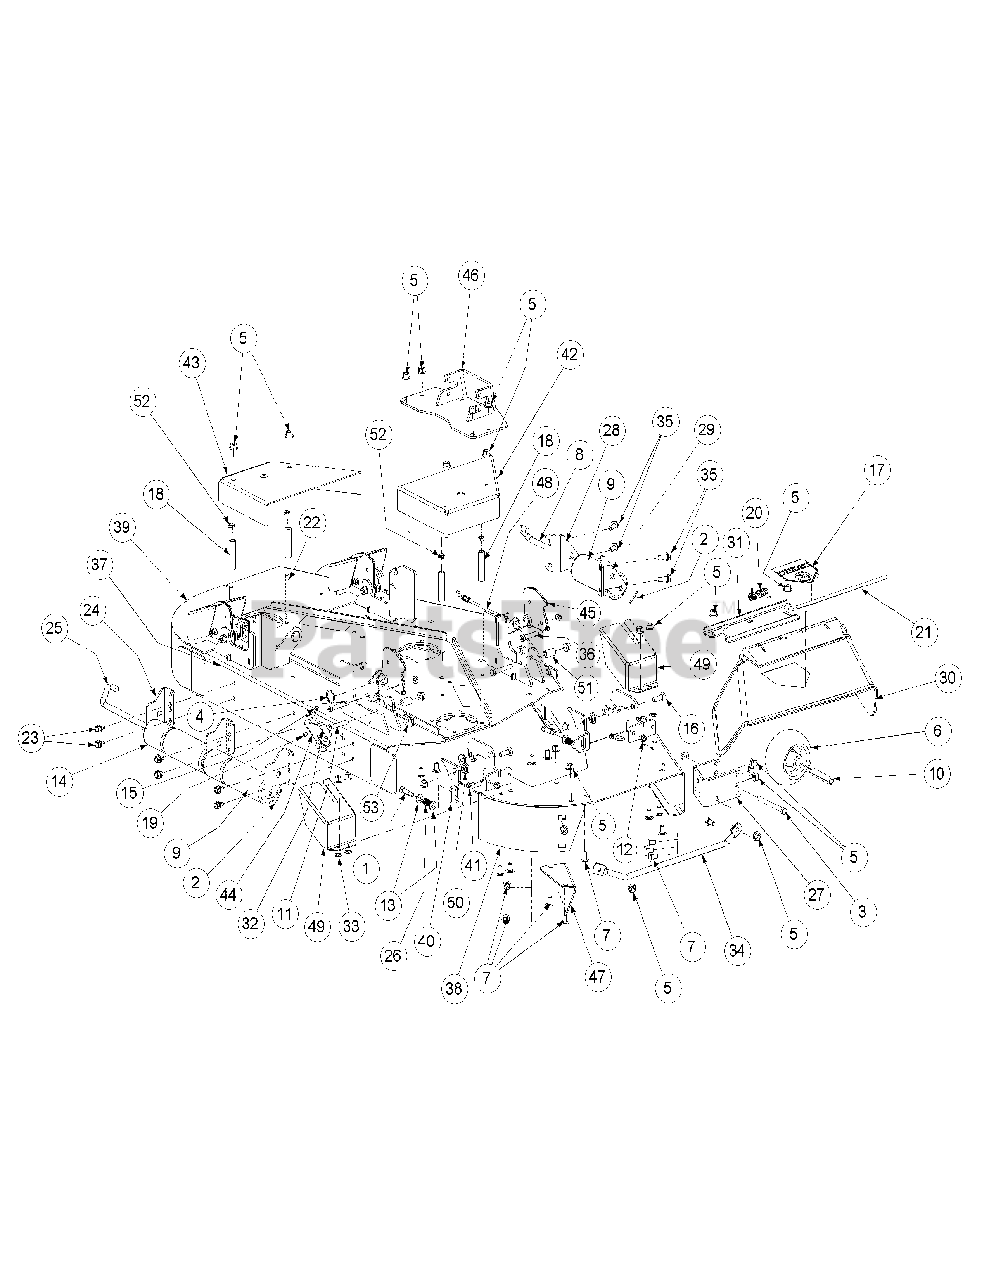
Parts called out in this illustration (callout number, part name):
1	Shoulder Bolt, .375 x 1.50
2	Cotter Pin, .125 Dia. x 1.0
3	Hex Cap Screw, 3/8-16, 3.75
4	Torsion Spring
5	Hex Nut Flange Lock, 3/8-16
6	Complete Wheel, 5.00 Dia
7	Carriage Bolt, 3/8-16 x .75 Lg
8	Roller Pin, 1/2 Dia x 7.31 Lg
9	Front Roller
10	Wheel Spacer
11	Hex Cap Screw, 3/8-16 x 2.50
12	Hex Flange Lock Nut, 5/16-18
13	Flat Washer, 3/8
15	Screw, TT, 10-24, .5
16	Carriage Screw, 3/8-16 x 1.25
17	Decal, Danger Hands and Feet
18	Spacer, .39 x .625 x 2.75
19	Lock Nut, #10-24
20	Torsion Spring, 0.4 ID x 2.16 LG
21	Chute Deflector Rod
22	Carriage Bolt, 3/8-16, 4.0
23	Hex Index Washer Screw, 3/8-16, .05
24	Fabricted Deck Roller Mount Bracket
25	Roller Rod
26	Lift Handle Spring
27	Front Anti-Scalp Wheel Mount Bracket
30	Deflector Chute
31	Chute Deflector Bracket
32	Spring Retainer
33	Push Retainer, 3/8
34	Fabricated Deck Finger Guard
35	Self Tapping Screw, 3/8-16 x 0.875
36	Shoulder Bolt 3/8 x 1.75
37	Fab Fold Deck Weldment
38	Fab Fold Wing Weldment, RH
39	Fab Fold Wing Weldment, LH
40	Pull Fold Hinge Lock
41	Screw, TT, 1/4-20 x .75
42	Belt Cover, RH
43	Belt Cover, LH
44	Handle Control Bracket
45	Lift Cable Bracket Weldment
46	Front Lift Bracket Weldment
47	Chute Baffle
48	Lift Cable
49	Lift Wing Shield
50	Spacer, 1.00 x .38 x .63
51	Pivot Spacer
52	Nut, 3/8-16, Jam
53	U-Nut, 3/8-16, .75
